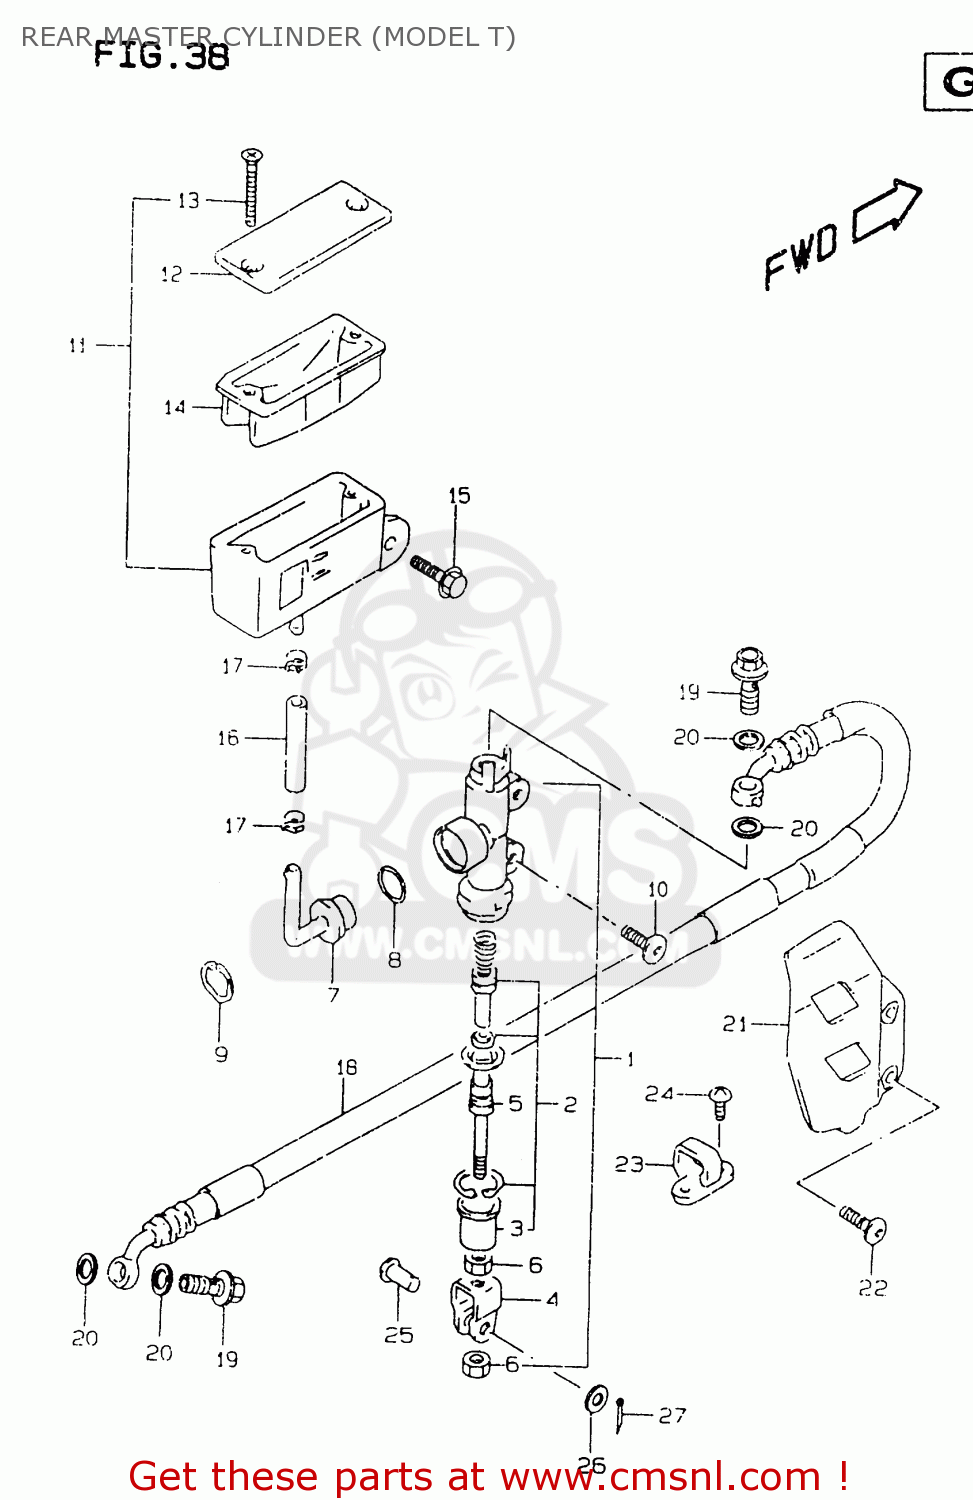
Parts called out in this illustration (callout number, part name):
1	CYLINDER ASSY,RR MASTER
2	PISTON/CUP SET
3	BOOT
4	YOKE
5	ROD,PUSH
6	NUT
7	CONNECTOR
8	O RING
9	CIRCLIP
10	SCREW(6X16)
11	TANK ASSY,RESERVOIR
12	CAP
13	SCREW
14	DIAPHRAGM
15	BOLT
16	HOSE,RESERVOIR TANK
17	CLAMP,RESERVOIR HOSE
18	HOSE COMP,REAR BRAKE
19	BOLT UNION
20	WASHER(10X15X1.5)
21	GUARD,RR MASTER CYLINDER
22	SCREW(6X16)
23	GUIDE,RR BRAKE HOSE
24	SCREW
25	PIN(8X20)
26	WASHER(8.5X13X1.6)
27	PIN
